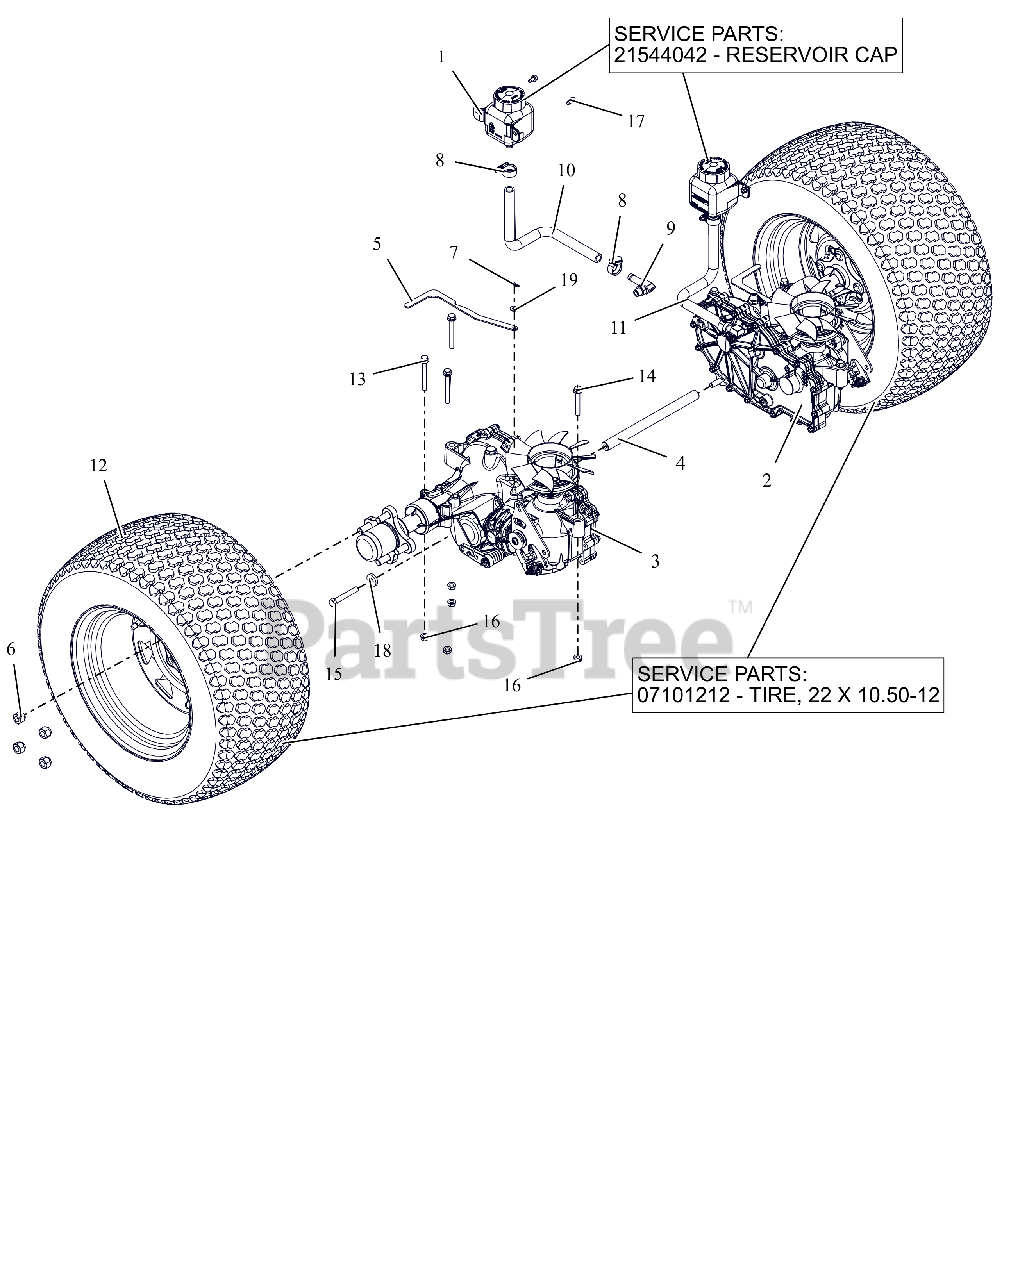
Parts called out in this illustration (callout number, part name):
1	TANK, EXPANSION
1	CAP, HYDRO RESERVOIR REPLAC.
2	TRANSAXLE, ZT3100 LH
3	TRANSAXLE, ZT3100 RH
4	SHAFT, TRANSAXLE SUPPORT
5	BRKT, VALVE DUMP
6	NUT, WHEEL .50-20 ZCC
7	PIN, HAIR #225 .072X1.09
8	CLAMP,.88 DIA. HOSE
9	FITTING, HYD (90 DEG)
10	HOSE, FORMED EXPANSION -HD RH
11	HOSE, FORMED EXPANSION -HD LH
12	ASM, WHL/TIRE 22X10.50-12 K500
12	TIRE, 22X10.50-12
13	BLT,HEX-FLG .31-18X2.75 G5 ZCC
14	BLT,HEX-FLG .31-18X2.25 G5 ZCC
15	BLT, HEX .38-16X2.50 G5 ZCC
16	NUT,LK-CTR-FLG .31-18 GF ZCC
17	SCR-TAP .25-20X.50 HWH ZCC
18	WSHR, FLT .406X1.00X.188 ZCC
19	WSHR,FLT .281X.625X.065 ZCC
